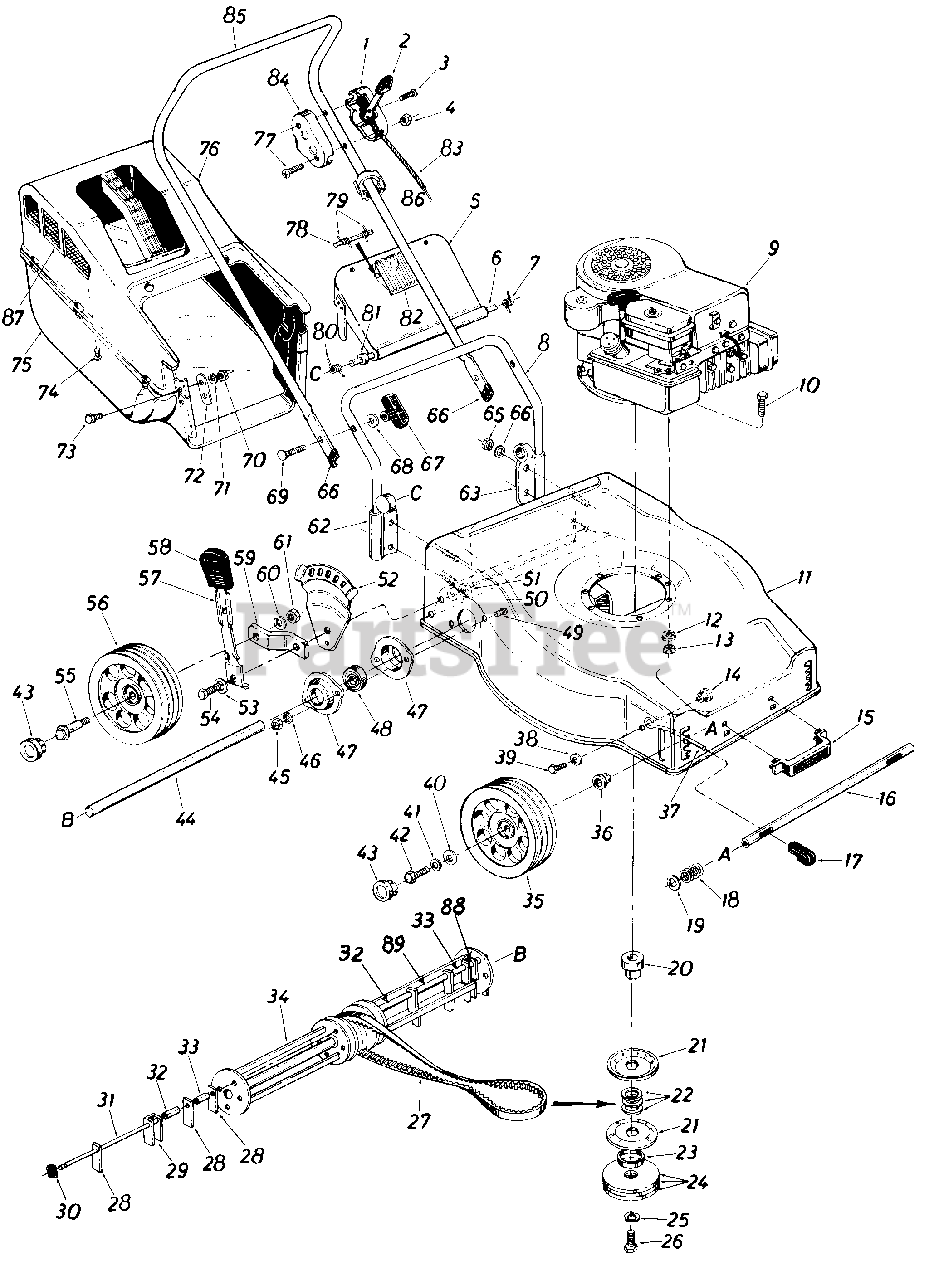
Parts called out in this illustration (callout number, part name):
1	Throttle Control Housing
2	Throttle Control Lever
3	Sheet Metal Screw M5 x 30
4	Hex Nut M5
5	Deflector-Chute
6	Pivot Shaft-Chute Deflector Door
7	Torsion Spring-L.H.
8	Lower Handle
9	Engine
10	Hex Bolt M8 x 30
12	Lock Washer B8
13	Hex Nut M8
14	Spacer
15	Deck Handle-Front
16	Front Axle
17	Knob-for Front Height Adj.
18	Compression Spring
19	Spring Spacer
20	Pulley Hub
21	Pulley "V" Belt
22	Spacers-
23	Spacer
24	Fly Wheel
25	Lock Washer
26	Hex Bolt 3/B" x 45 UF
27	"V"-Belt
28	Thatcher Blade
29	Lift Blade
30	Snap Ring 8M
31	Thatcher Blade Shaft
32	Spacer
33	Spacer
34	Thatcher Rotor
35	Front Wheel
36	Spring Spacer
37	Front Height Adjustment Lever
38	LockWasher B6
39	Hex Bolt M6 x 12
40	Flat Wash 015
41	Belleville Washer M12
42	Hex Bolt M12 x 16
43	Hub Cap
44	Thatcher Blade Shaft
45	Hex Nut M6
46	Lock Washer M6
47	Flange Bearing w/Housing
49	Mach. Screw M6 x 16
50	Lock Washer B10
51	Hex Nut M10
52	Index Plate
53	Belleville Washer
54	Hex Bolt M 10 x 20
55	RearWheel Axle Bolt
56	Rear Wheel
57	Spring Lever w/Knob
59	Pivot Bracket
60	Lock Washer B10
61	Hex Nut M10
62	Handle Bracket-R.H.
63	Handle Bracket-L.H.
64	Flat Washer 8.4
65	Hex Nut M8
66	Handle Cap
67	Wing Nut M6
68	Lock Washer 6.4
69	Mach. Screw M6 x 50
70	Hex Nut
71	Lock Washer
72	Reinforcement Plate
73	Mach. Screw B3.92 x 32
74	Mach. Screw Self Tap B3.9 x 9.5
75	Grass Bag-Lower Half
76	Grass Bag-Upper Half
77	Screw B2.9 x 9.5
78	Pivot Pin
79	Torsion Spring for DoorSnap
80	Torsion Spring-R.H.
81	Spring Spacer
82	Door Snap
83	Throttle Control Wire
84	Throttle Control Housing
85	Upper Housing
86	Cable Tie
87	Screen
88	Spacer 1/2" Lg.
89	Spacer 1 3/4" Lg.
